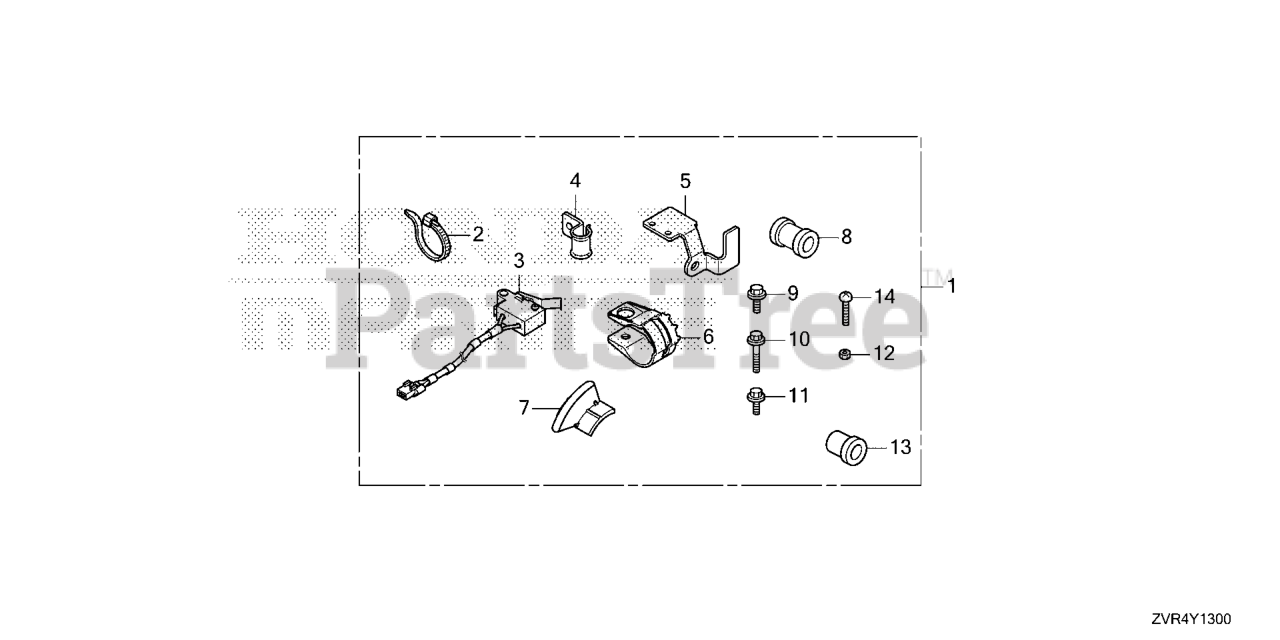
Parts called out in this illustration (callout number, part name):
1	TILT LIMIT KIT
2	BAND (BLACK 3.5X140)
3	SW ASSY., TILT LIMIT
4	CLAMP, TUBE A
5	BRACKET
6	CAM A
7	CAM B
8	GROMMET, CODE
9	BOLT, FLANGE (6X12) Use from Frame SN 1005249.
10	BOLT, FLANGE (5X25)
11	BOLT, FLANGE (5X12)
12	NUT, U (3MM)
13	COLLAR
14	SCREW, PAN (3X14)
